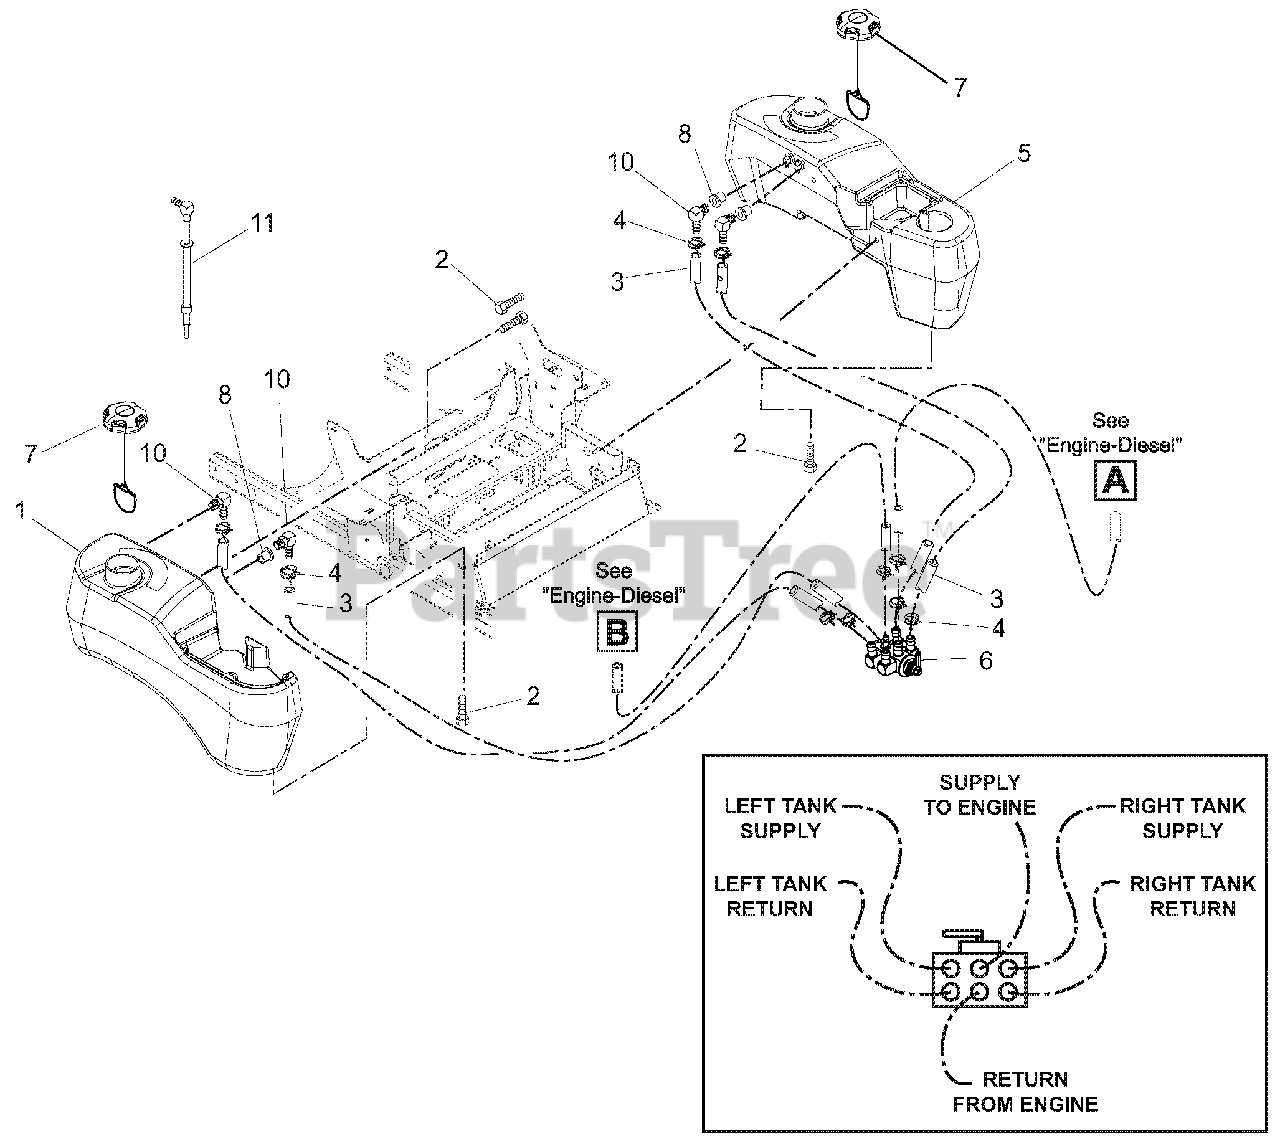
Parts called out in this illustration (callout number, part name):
1	TANK, RIGHT HAND FUEL
2	BOLT, SEMS .31-18 X .62
3	HOSE, .31 ID
4	CLAMP, HOSE WIRE .52/.55
5	TANK, LEFT HAND FUEL
6	VALVE, FUEL
7	CAP, FUEL YELLOW DIESEL TETHER
8	GROMMET, ORANGE
10	FITTING, TANK
11	26" FUEL LINE KIT DIESEL (INSIDE TANK)
